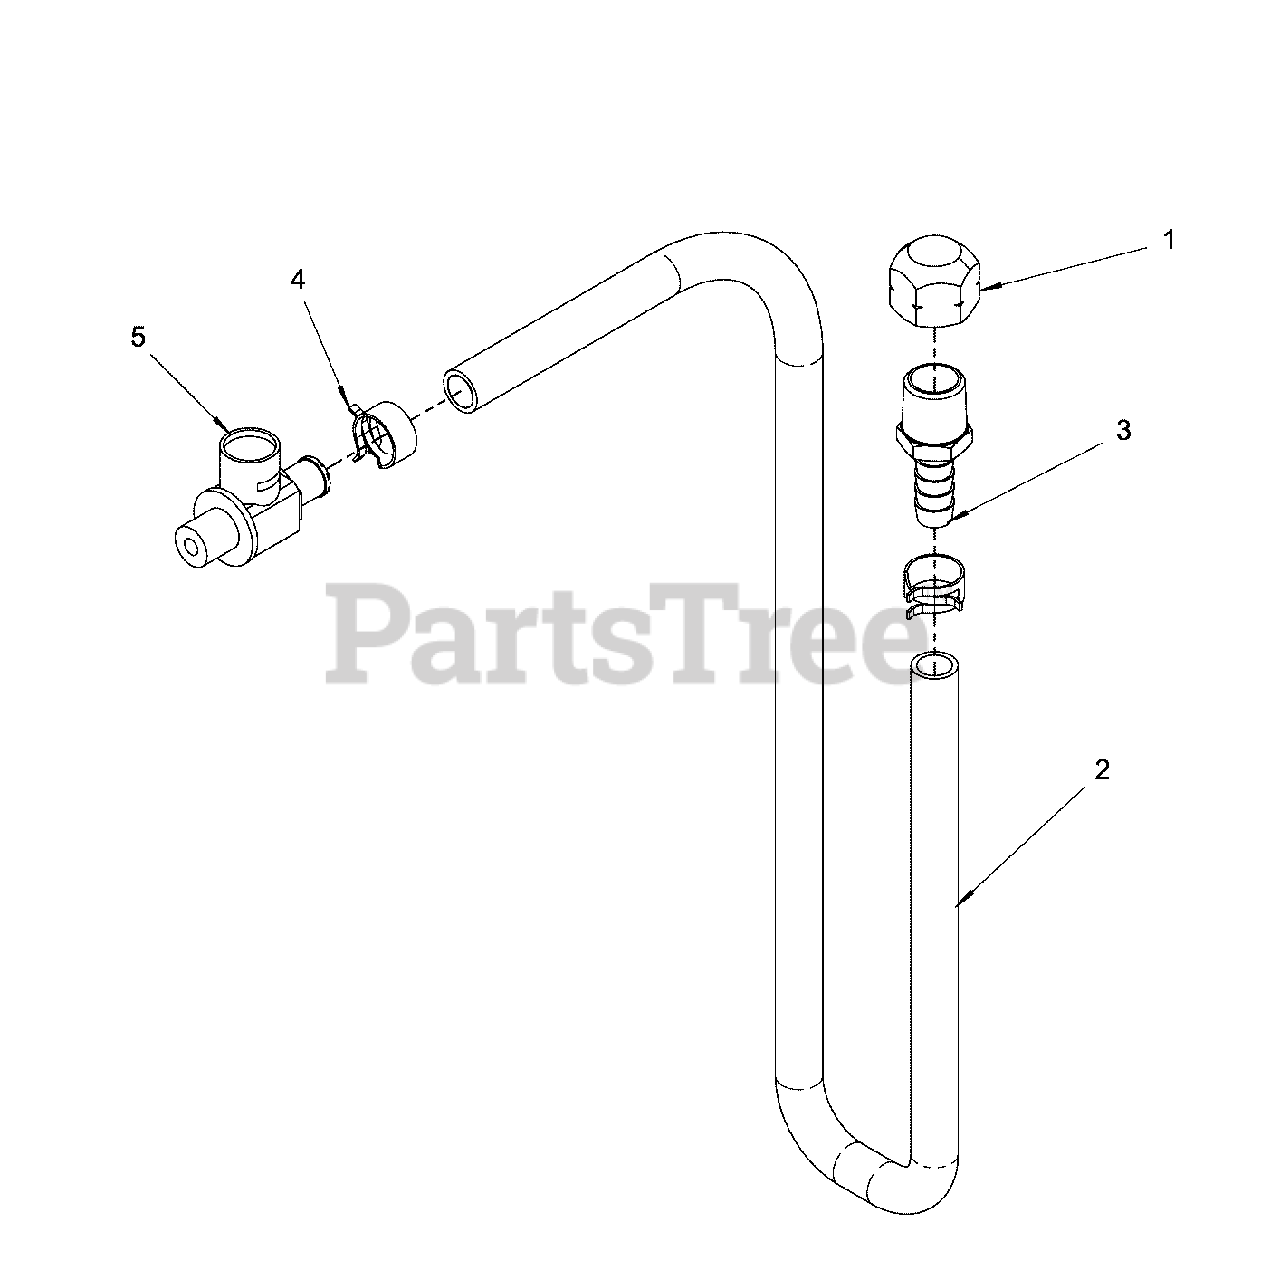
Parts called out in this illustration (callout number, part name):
1	CAP
2	HOSE, FUEL, 22"
3	FITTING
5	VALVE, OIL DRAIN
